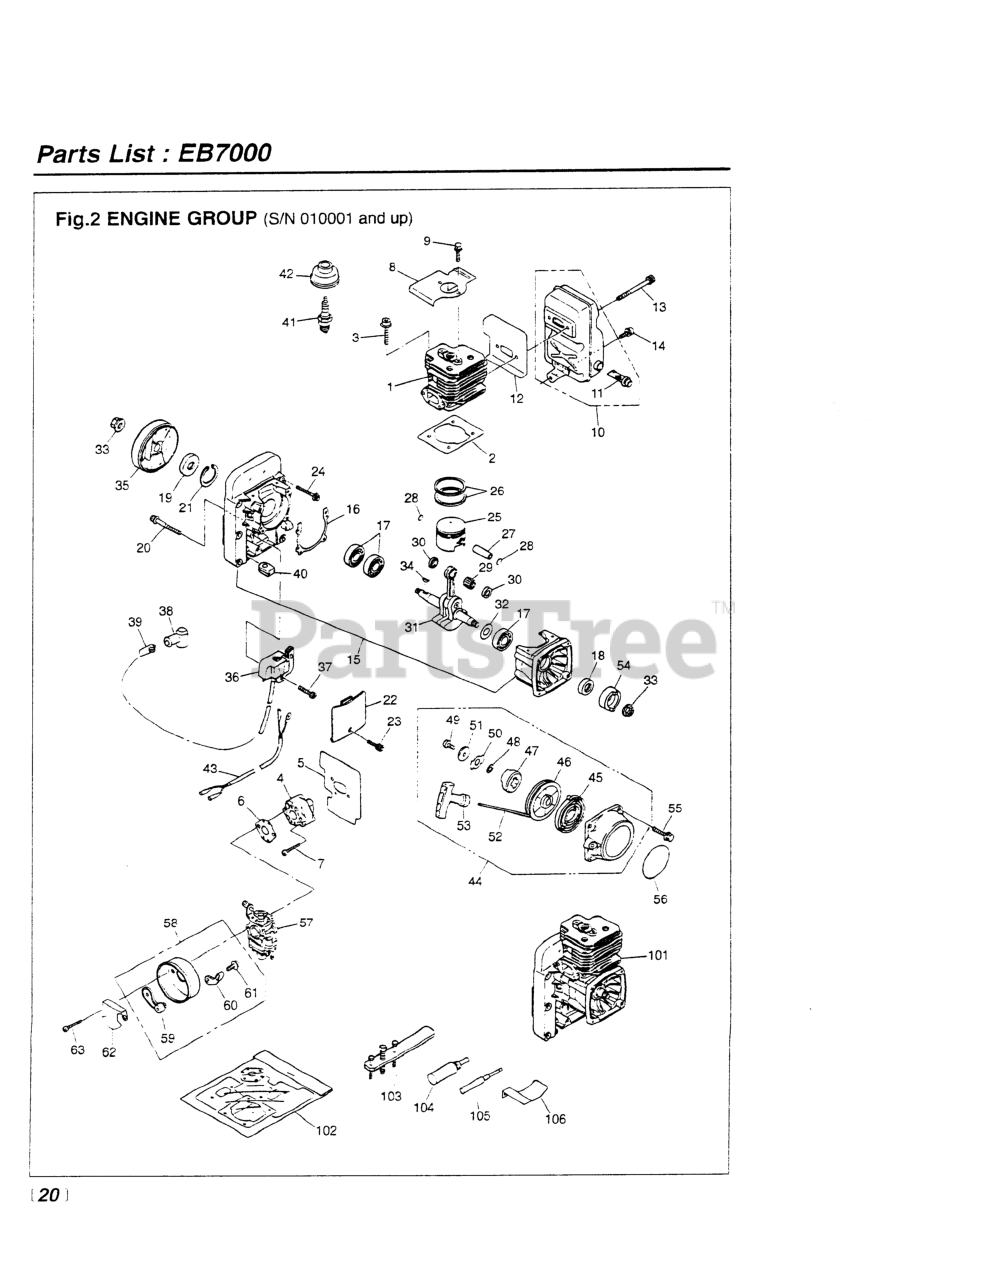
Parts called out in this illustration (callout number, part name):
2	GASKET, BASE
3	BOLT, M5 X 22
5	GASKET
6	GASKET, CARB (RPLS -13131)
7	SCREW, M5 x 35
8	COVER
9	BOLT, M5 x 10
11	ARRESTER
12	GASKET
13	BOLT, M6 X 70
14	BOLT, M6 X 12
15	CRANKCASE (USE 2750-21101)
16	GASKET
18	SEAL, OIL - STARTER SIDE
20	BOLT, M5 X 30
21	RING, SNAP, M35 X 1.5
22	COVER
23	BOLT, M4 X 16
24	BOLT, M6 X 40
25	PISTON
26	RING
27	PIN, PISTON
28	RING, SNAP
29	BEARING
30	WASHER (RPLS 1491-41510)
32	SHIM (REPLACES 848-870-G000)
33	NUT, M10
34	KEY
35	ROTOR (USE 2750-71111)
36	COIL ASSEMBLY, IGINITION
37	BOLT, M4 x 20
38	CAP
39	SPRING
40	GROMMET
42	CAP
43	CORD COMP.
45	SPRING (RPLS -75220)
47	DOG
48	WASHER
49	SCREW
50	RETAINER (RPLS 1861-75161)
51	WASHER
52	ROPE
53	KNOB
54	PULLEY (RPLS -75210)
55	BOLT, M5 x 20
57	CARBURETOR (WYK-123-1)
62	PLATE
63	SCREW (RPLS 0263-30550)
102	KIT, GASKET
103	PULLER ASSY
104	STOPPER (TOOL) (RPLS 3320-9641
105	GUIDE (TOOL)
